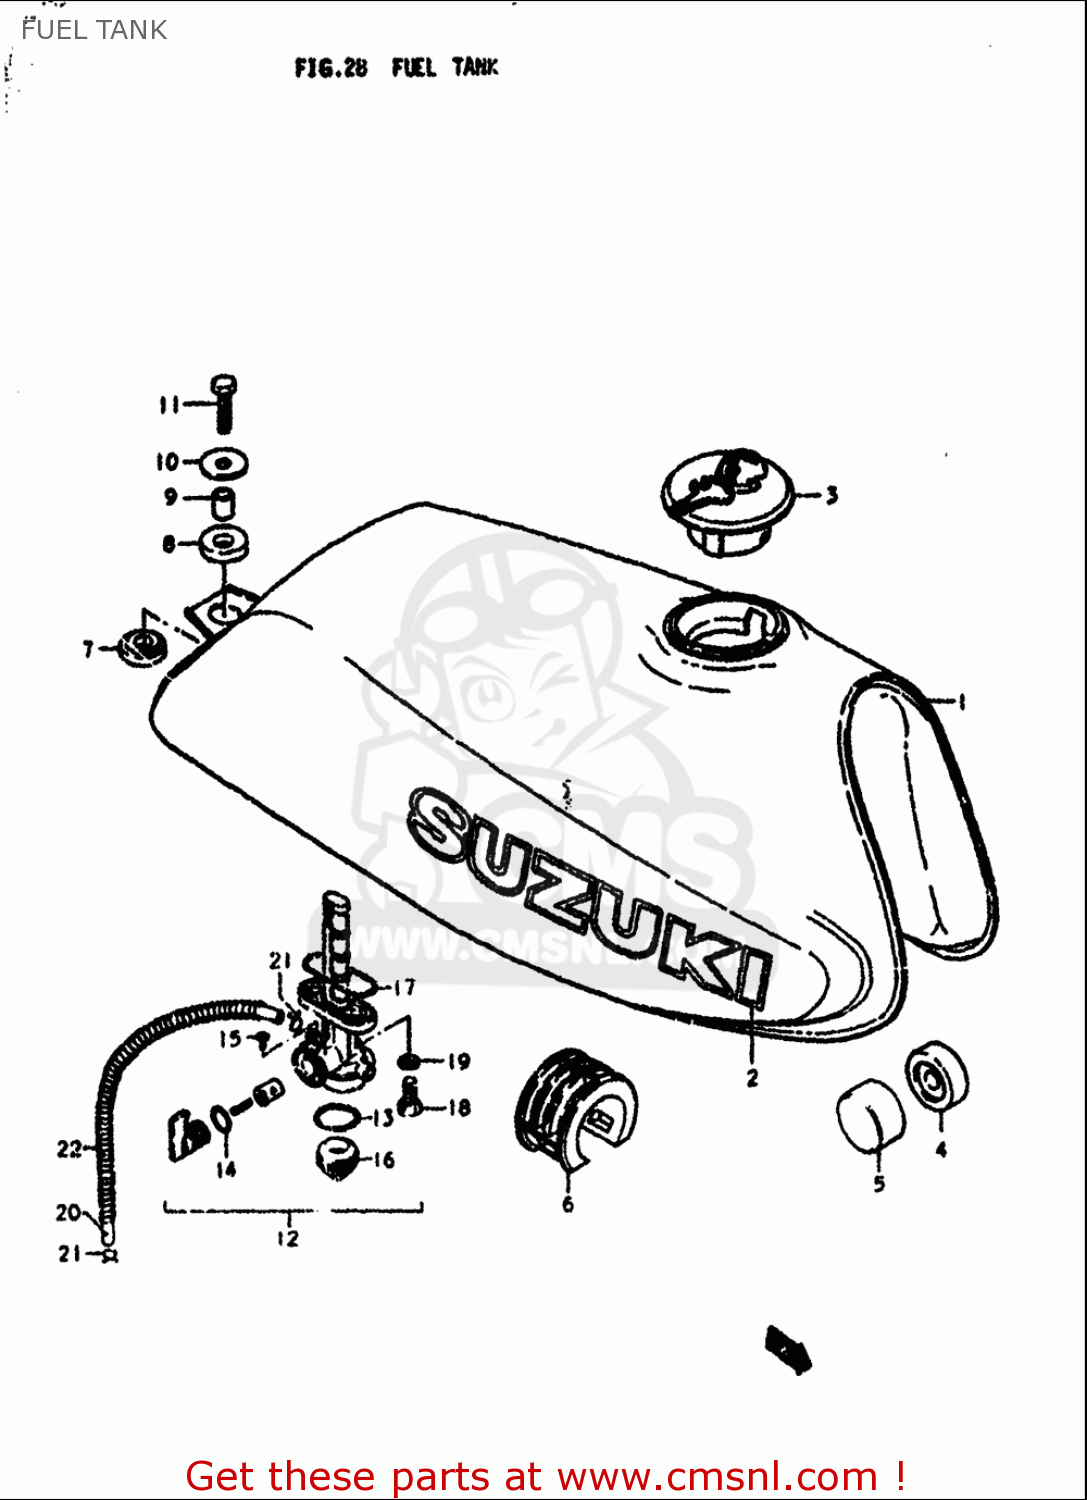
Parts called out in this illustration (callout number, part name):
2	EMBLEM(WHITE)
3	CAP SET,FUEL TANK
4	CUSHION
5	CUSHION
6	CUSHION,FUEL TANK
7	BUSH(12X15X20)
8	CUSHION
9	SPACER(8.5X12X15)
10	WASHER(8.5X28X1.6)
11	BOLT
12	COCK ASSY,FUEL
13	GASKET,FILTER (NAS)
14	O RING,LEVER
15	SCREW,FUEL COCK LEVER
16	CUP,STRAINER
17	O RING,FUEL COCK
18	SCREW
19	GASKET(5.8X13X1.2) (NAS)
20	HOSE(7X10.2X2000)
21	CLIP
22	SPRING
